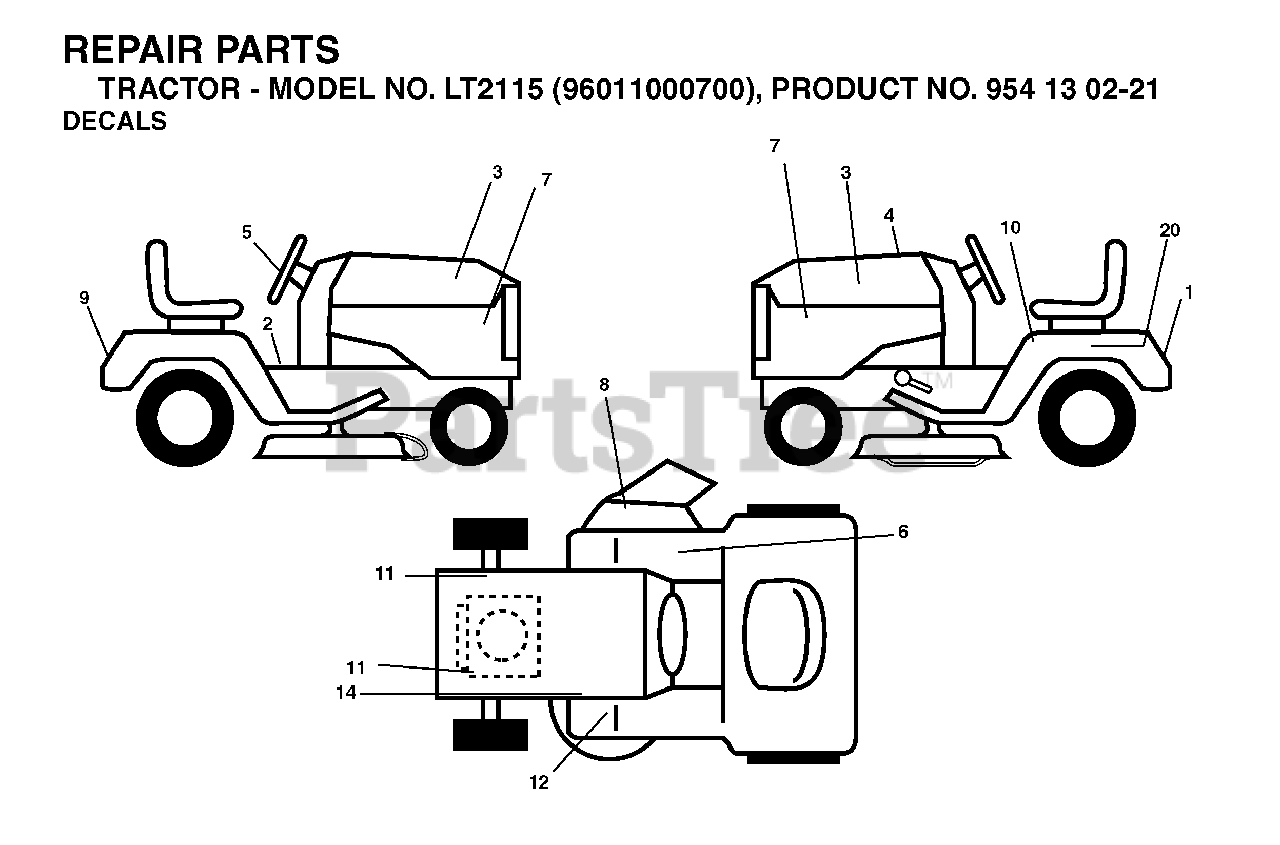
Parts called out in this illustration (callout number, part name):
2	DECAL PARK BRAKE
8	DECAL.INTERNATIONL.CUTFINGER
10	DECAL READ OWNER'S MAN SYMS
14	DECAL V-BELT SCHEMATIC
20	DECAL BTRY SYMBOLS
